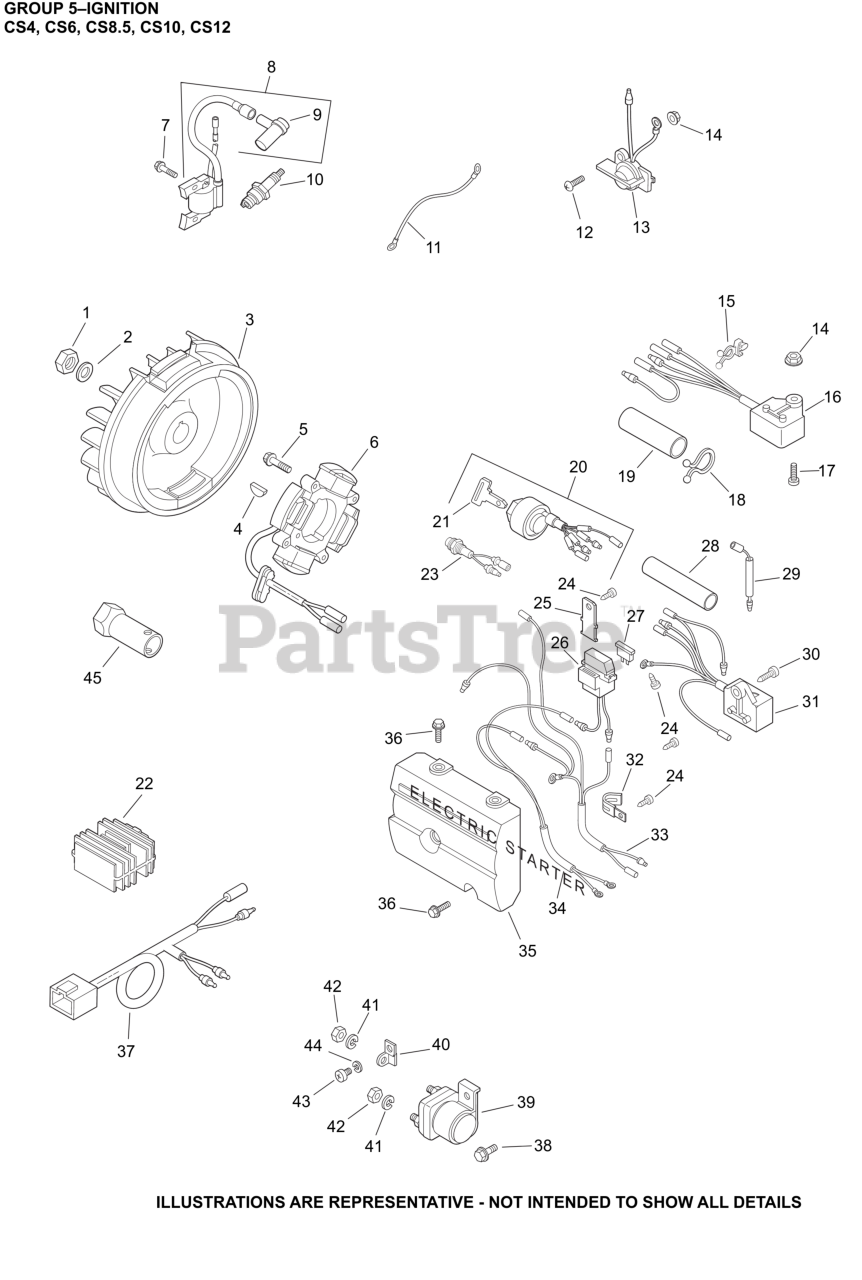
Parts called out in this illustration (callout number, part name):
1	NUT, FLYWHEEL
2	WASHER, F.W.
3	FLYWHEEL, MANUAL ST - (#DSC)
4	KEY, WOODRUFF
8	IGNITION MODULE KIT-USE 63 755 40-S
9	CAP ASSEMBLY
10	SPARK PLUG
11	LEAD,KILL
13	STOP SWITCH
14	NUT, STOP SWITCH-DISCONTINUED
15	CLAMP, WIRE
16	OIL SWITCH ASSEMBLY -USE 63 099 03-S
19	SLEEVE, WIRING
23	OIL LIGHT
